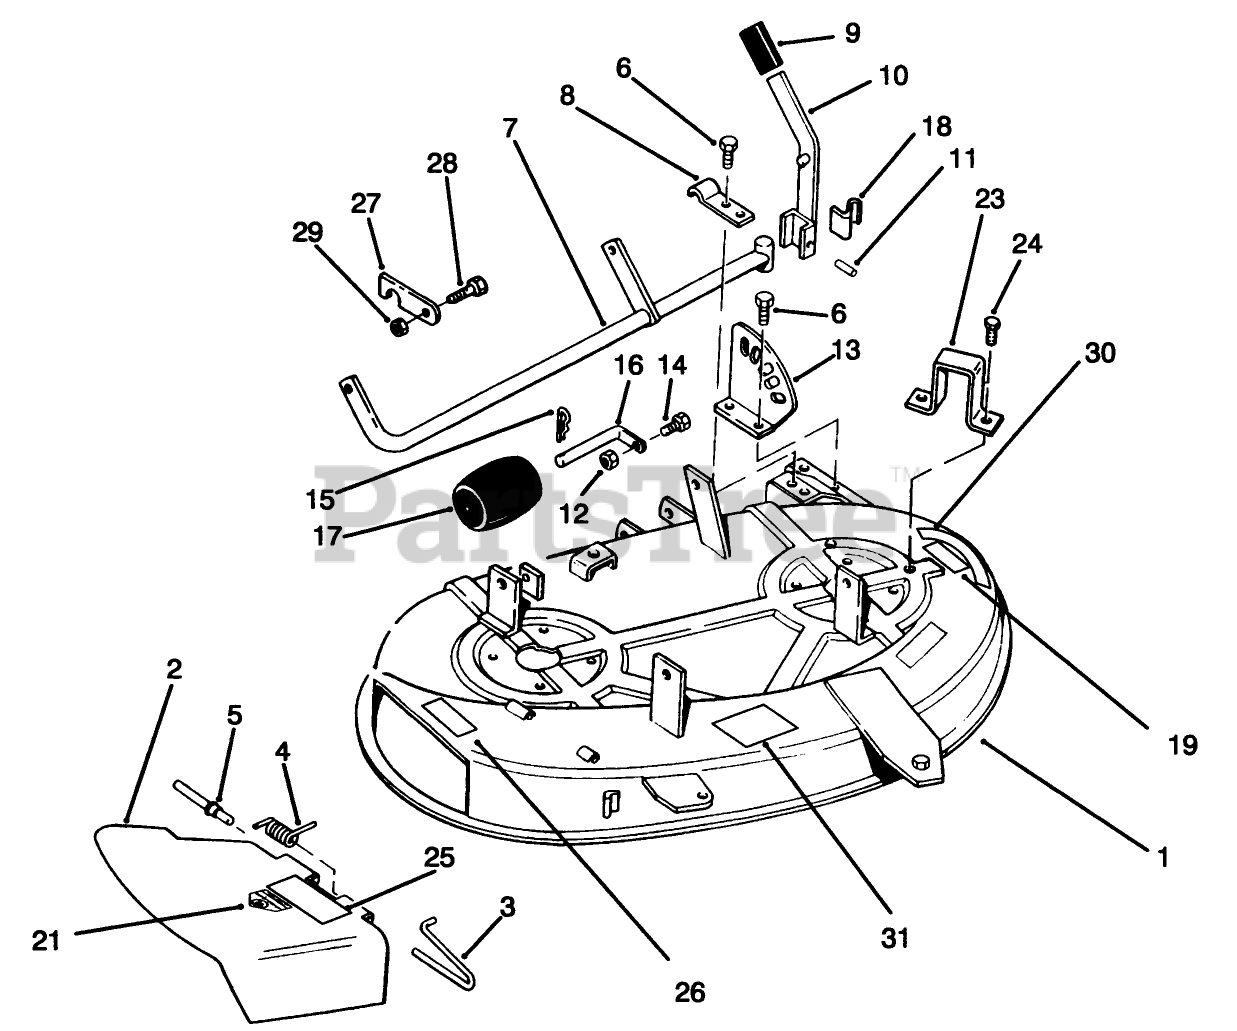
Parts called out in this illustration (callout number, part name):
3	ROD-HINGE FRONT
4	SPRING-TORSION
5	ROD-HINGE REAR
6	Bolt
11	SPIROL PIN 3/8X1 1/2
12	NUT-LOCK, NI
14	SCREW-HH
15	PIN-COTTER
17	ROLLER
18	CLIP-SPRING
19	DECAL-HOC
25	DECAL-DANGER, THROWN OBJECT
26	DECAL-DANGER
28	SCREW-HH
29	NUT-LOCK, NI
30	DECAL - DANGER
